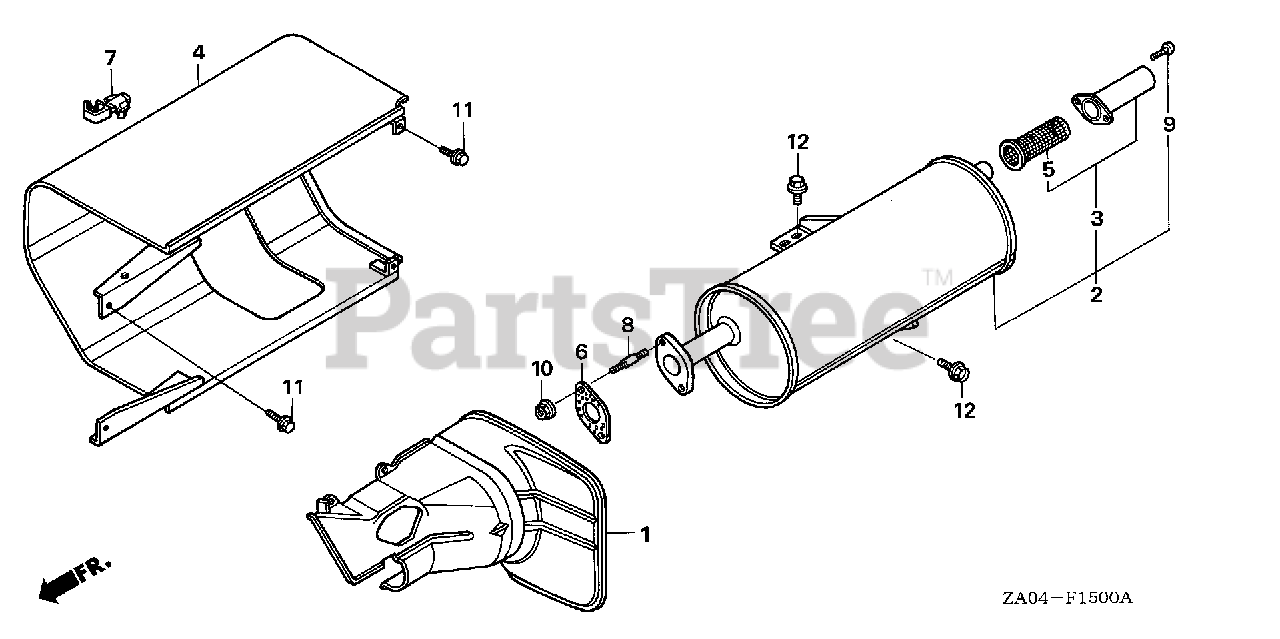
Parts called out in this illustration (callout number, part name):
2	MUFFLER
2	MUFFLER (NOT AVAILABLE)
3	CAP SET, ARRESTER
3	CAP SET, ARRESTER (NOT AVAILABLE)
4	SEPARATOR, MUFFLER
5	ARRESTER, SPARK
6	GASKET, MUFFLER
8	BOLT, STUD (8X35)
9	SCREW, PAN (5X8)
10	NUT, FLANGE (8MM)
11	BOLT, FLANGE (6X12)
12	BOLT, FLANGE (8X20)
